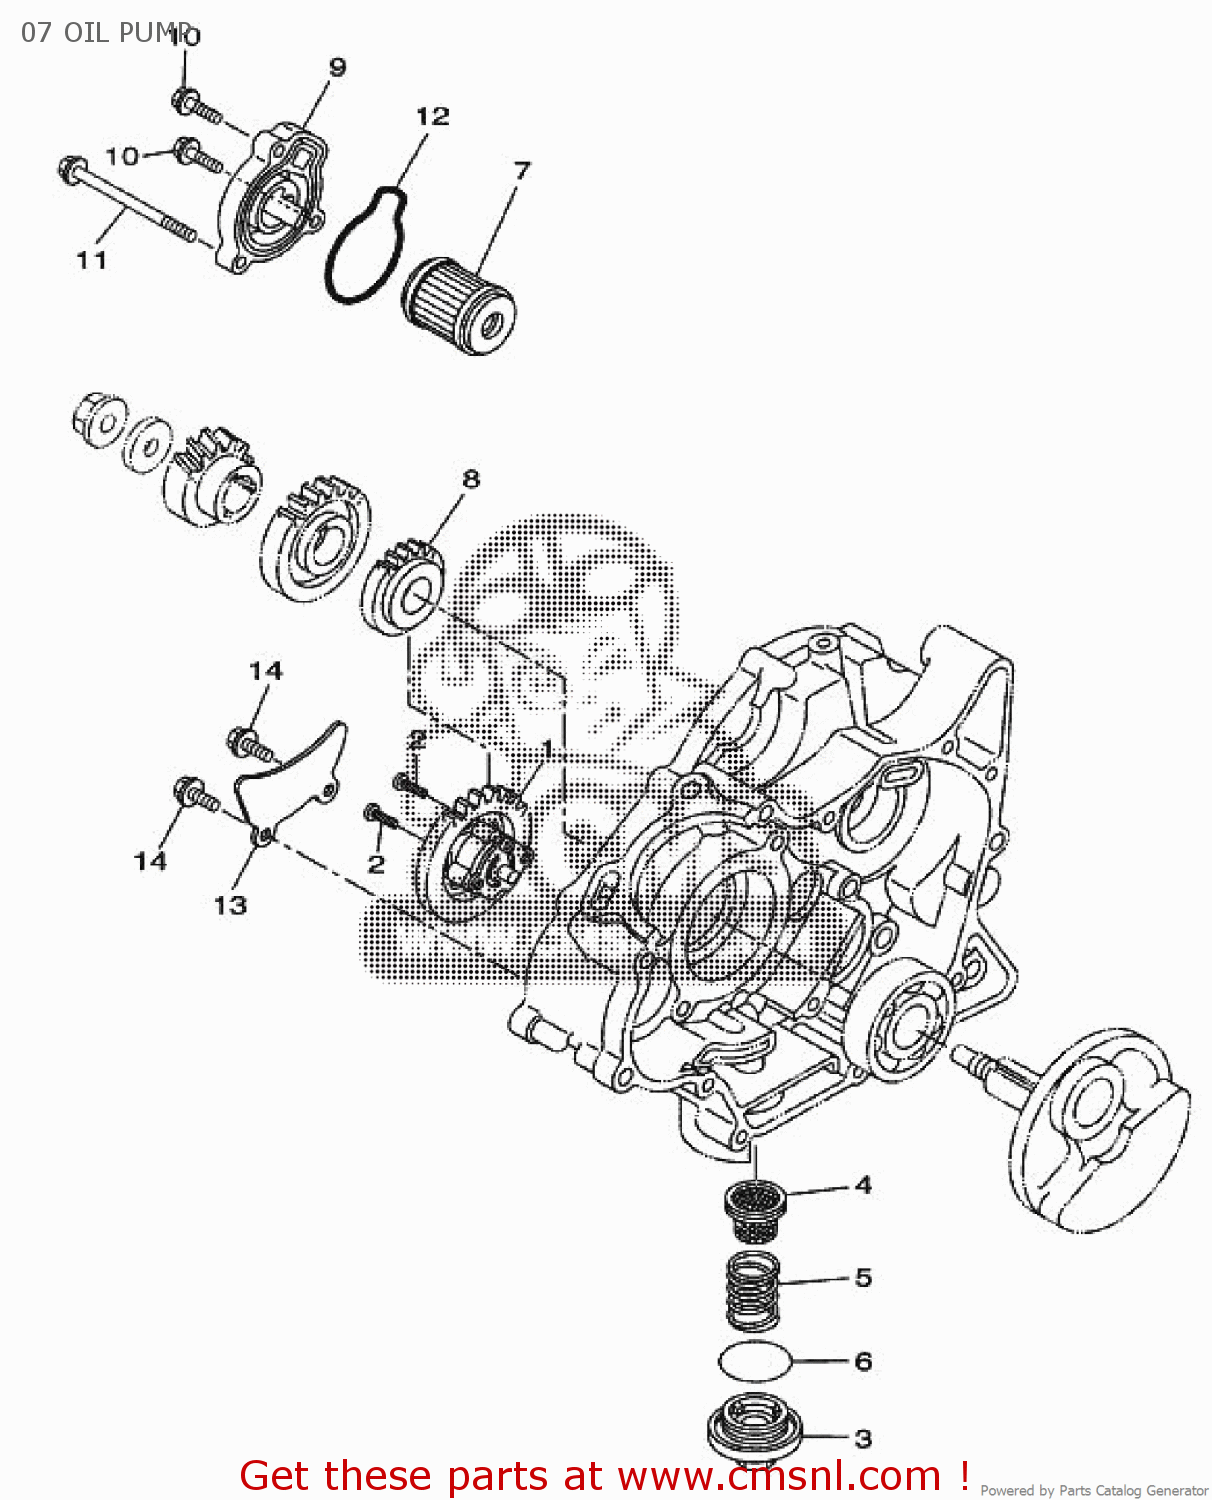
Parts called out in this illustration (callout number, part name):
1	OIL PUMP ASSY
2	SCREW, PAN HEAD(4MY)
3	PLUG, DRAIN
4	STRAINER, OIL
5	SPRING, COMPRESSIO
6	O-RING
7	ELEMENT ASSY, OIL CLEANER
8	GEAR, PUMP DRIVE
9	COVER, OIL ELEMENT
10	BOLT, FLANGE
11	BOLT, FLANGE
12	O-RING
13	COVER, PUMP GEAR
14	BOLT, FLANGE
